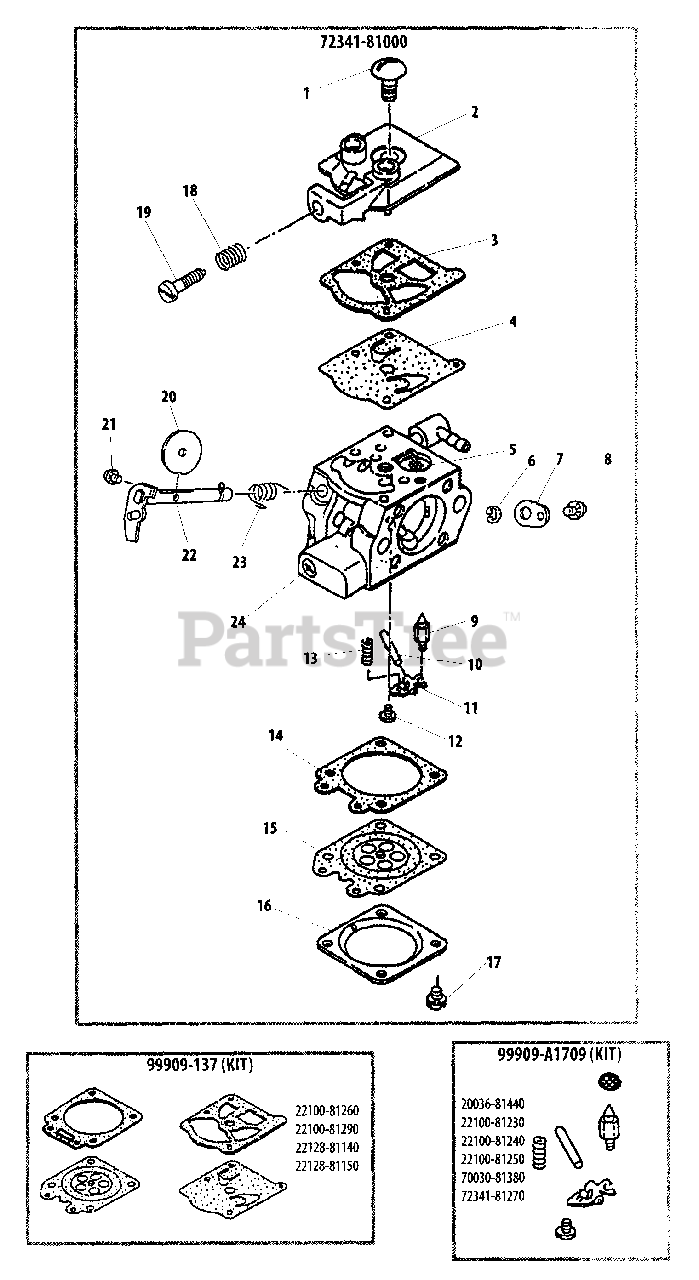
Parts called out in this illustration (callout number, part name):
1	SCREW
2	COVER ASSY, PUMP
3	GASKET, PUMP
4	DIAPHRAGM, PUMP
5	SCREEN, FUEL INLET
6	E-RING
7	LEVER, THROTTLE
8	SCREW
9	VALVE, INLET NEEDLE
10	PIN, METERING LEVER
11	LEVER, METERING
12	SCREW, METERING LEVER PIN
13	SPRING, METERING LEVER
14	GASKET, METERING DIAPHRAGM
15	DIAPHRAGM, METERING
16	COVER, METERING DIAPHRAGM
17	SCREW
18	SPRING, IDLE ADJUST
19	SCREW, IDLE ADJUST
20	VALVE, THROTTLE
21	SCREW ASSY
22	SHAFT, THROTTLE
23	SPRING, THROTTLE RETURN
24	LIMITER CAP, L SPEED
72341-81000	CARBURETOR
99909-137	DIAPHRAGM/GASKET KIT
99909-A1709	REPAIR KIT
